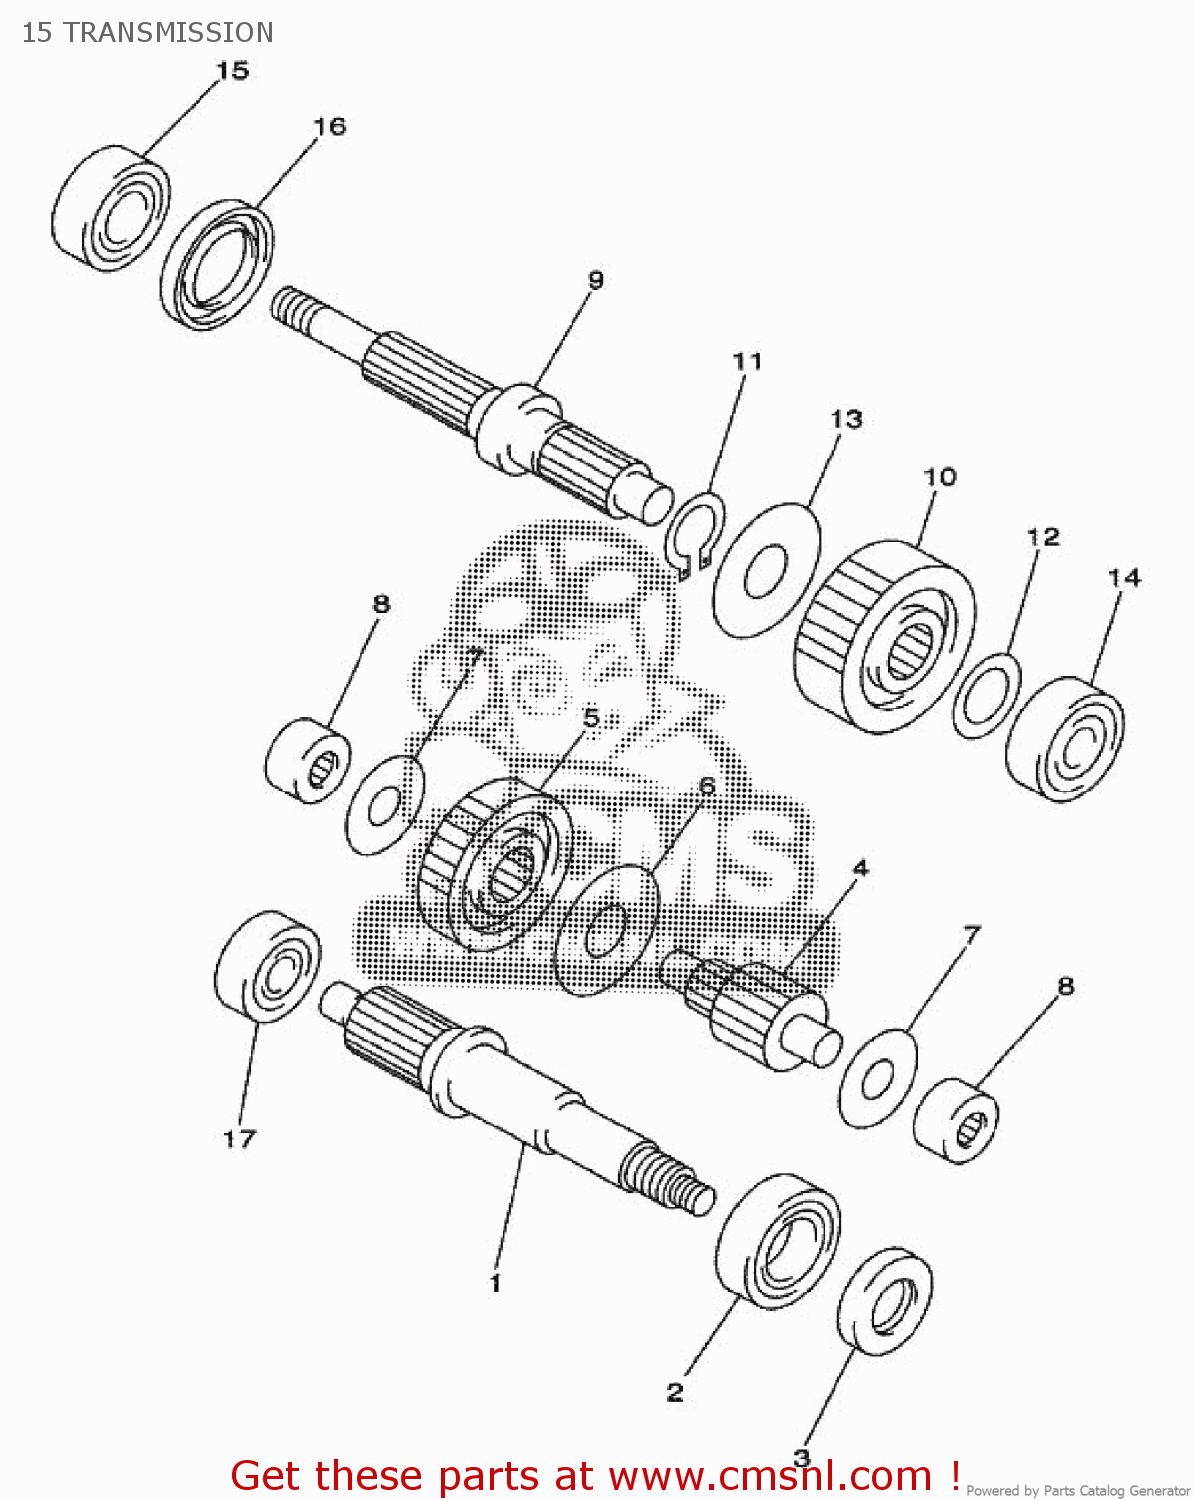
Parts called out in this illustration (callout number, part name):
1	GEAR, PRIMARY DRIVE
2	BEARING
3	OIL SEAL(1JY)
4	AXLE, MAIN
5	GEAR, PRIMARY DRIVEN
6	WASHER, CONICAL SP
7	WASHER, PLATE
8	BEARING
9	AXLE, DRIVE
10	GEAR, 1ST WHEEL
11	CIRCLIP
12	WASHER, PLATE
13	WASHER, CONICAL SP
14	BRG,R-B 6000 26MM 19G NT
15	BEARING
16	OIL SEAL
17	BRG,R-B 6000 26MM 19G NT
